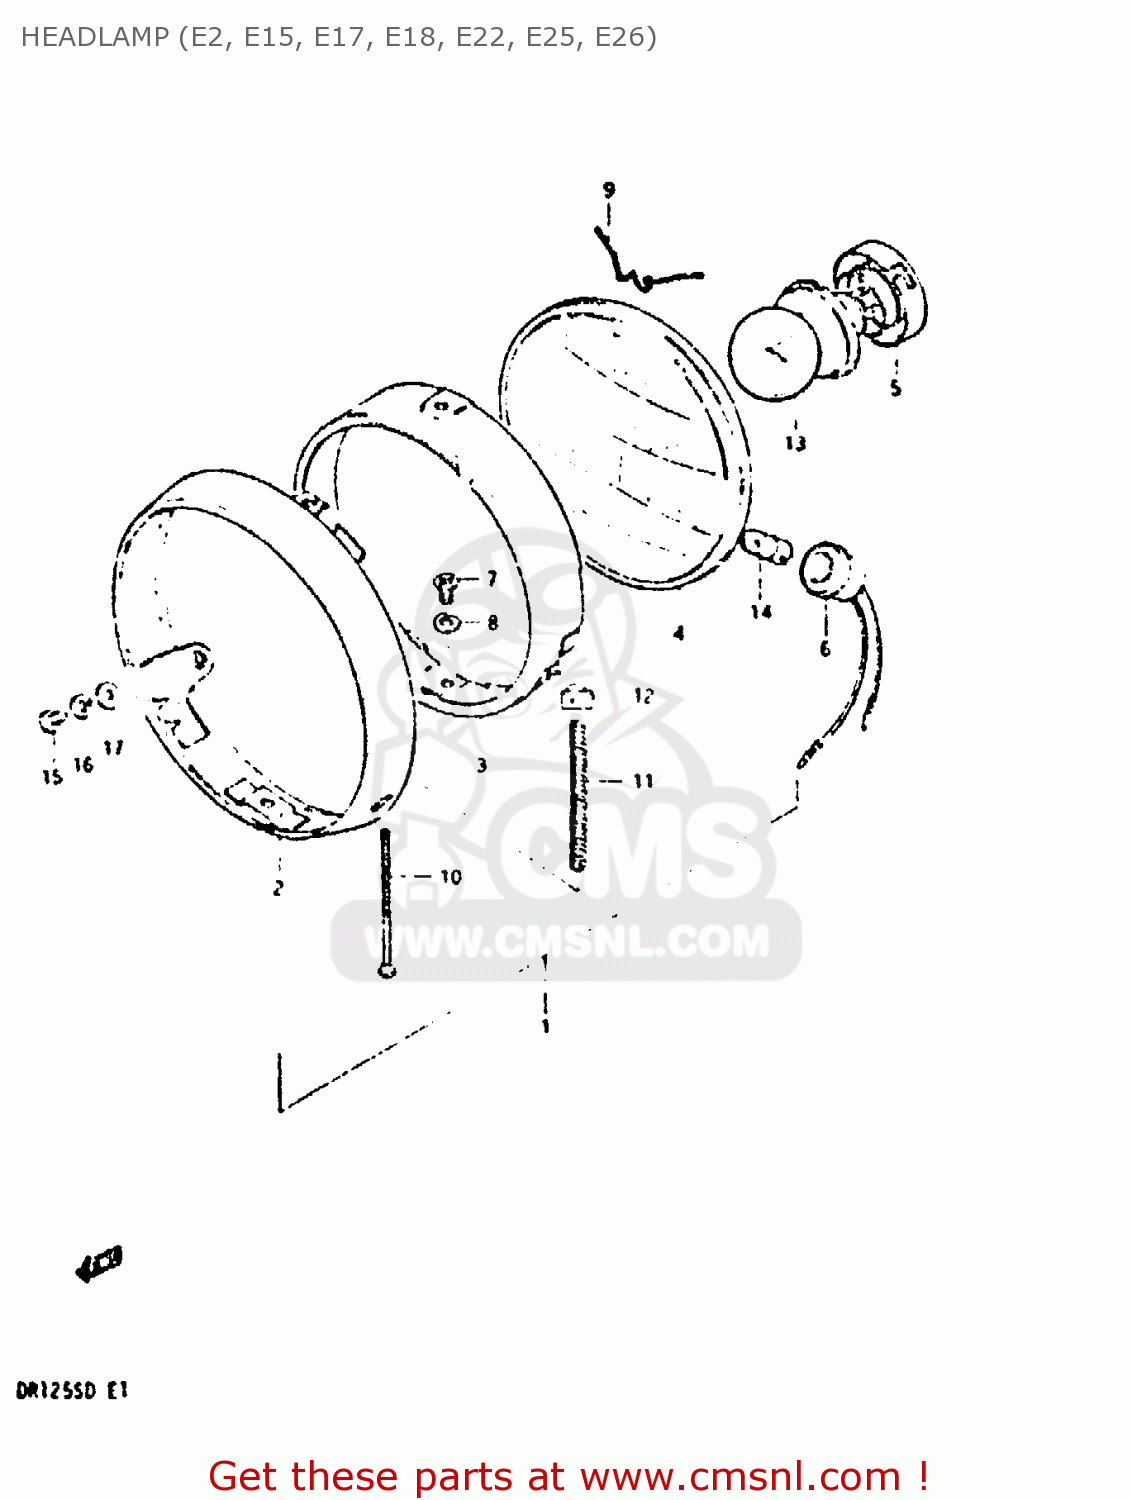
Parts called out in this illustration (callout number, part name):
1	HEADLAMP ASSY
2	RIM,HEADLAMP
3	RETAINER
4	LAMP UNIT
5	SETTER,BULB
6	SOCKET
7	SCREW
8	LOCK WASHER
9	SPRING
10	SCREW
11	SPRING
12	NUT
13	BULB(12V45/40W)
14	BULB(12V4W)
15	SCREW
16	LOCK WASHER
17	WASHER
